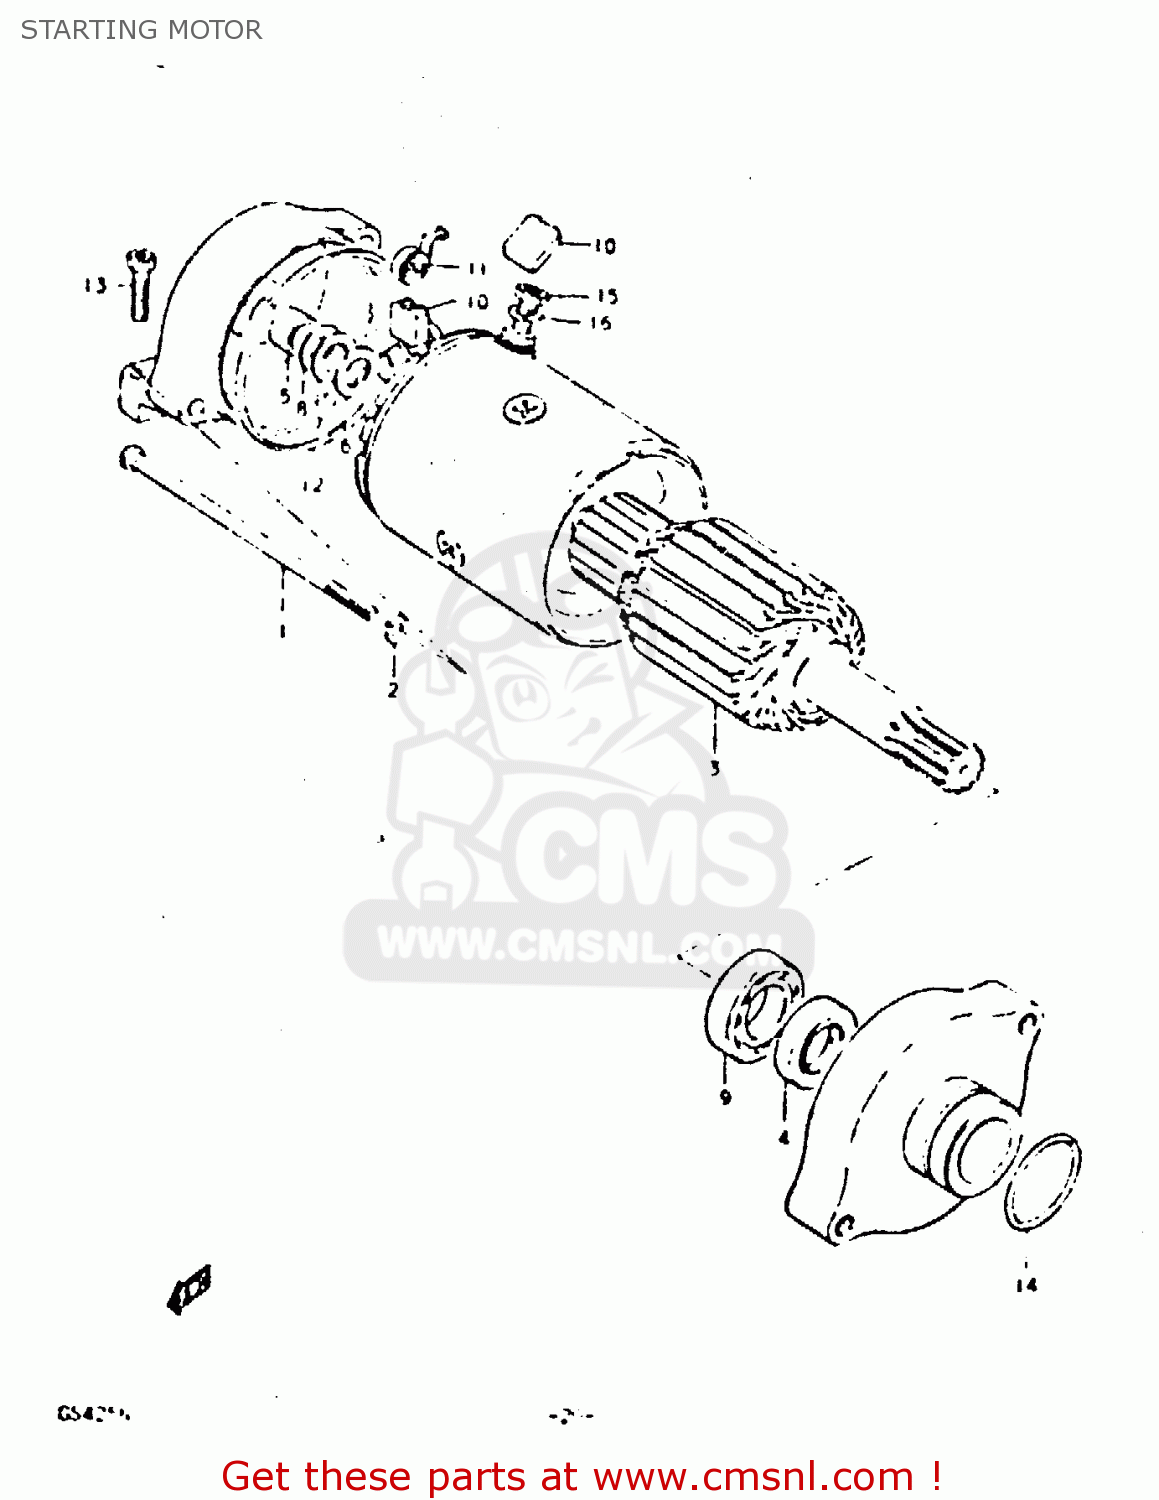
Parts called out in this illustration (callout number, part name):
1	BOLT
2	LOCK WASHER
3	ARMATURE
4	SEAL,OIL
5	BUSHING
6	SHIM, (1)
7	SHIM, (2)
8	SHIM, (3)
9	BEARING
10	BRUSH(-)
11	SPRING
12	GASKET
13	SCREW
14	O RING(D:2,ID:24.5)
15	NUT 6MM
16	LOCK WASHER
